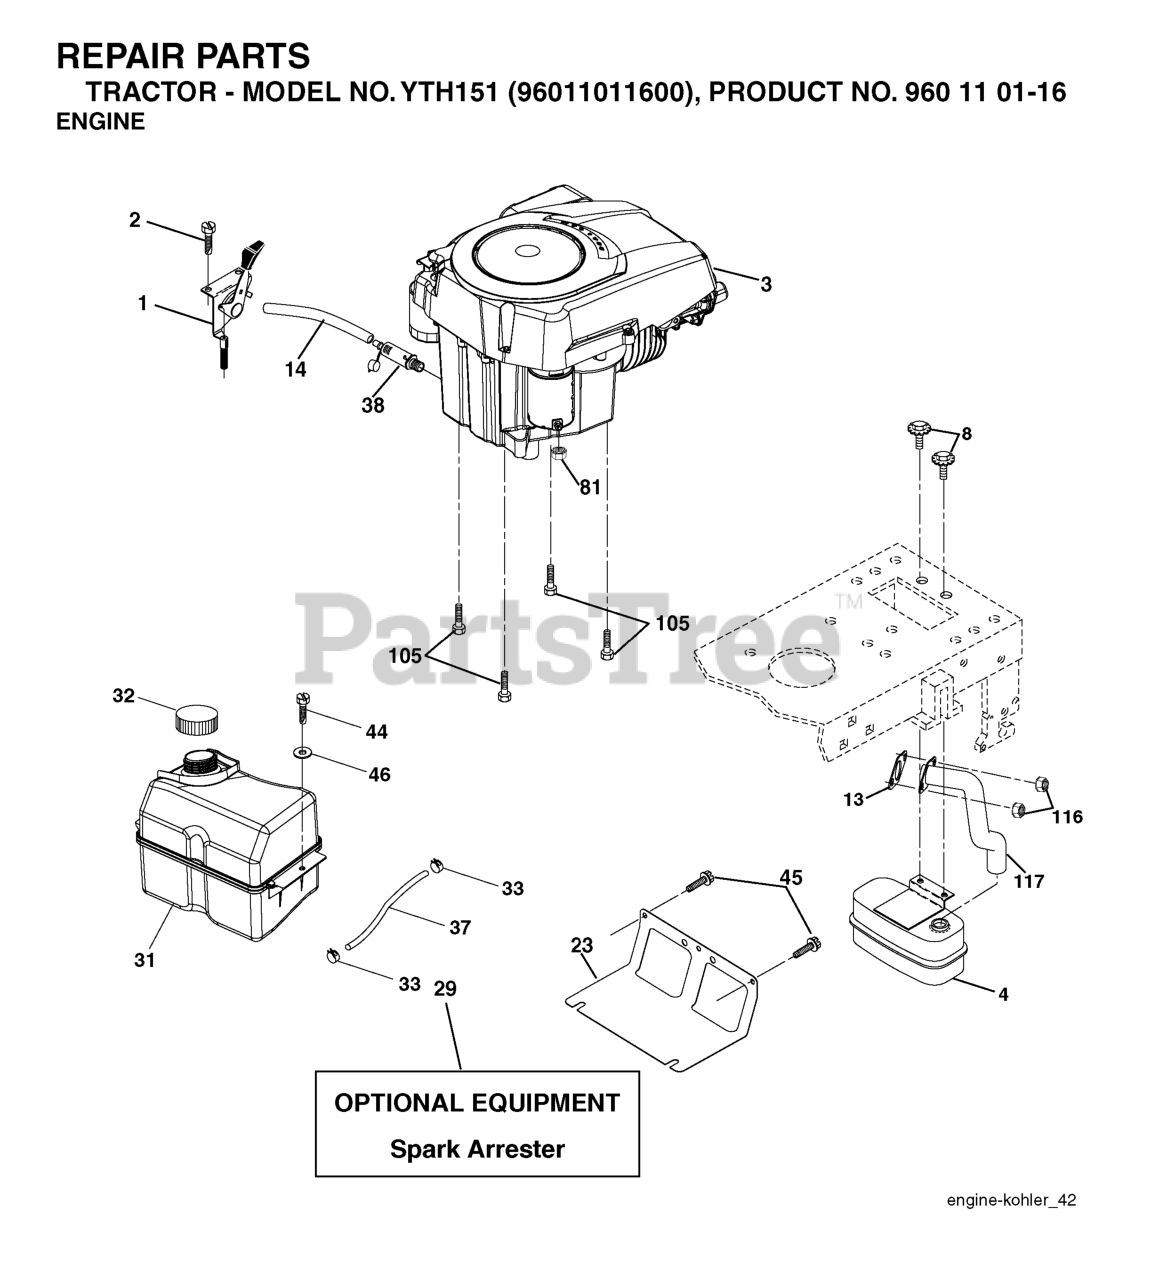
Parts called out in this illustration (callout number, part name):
1	CONTROL.THROTTLE.LT/YT
2	SCREW
4	MUFFLER.SINGLE.CYL.KOHL/B&S
8	BOLT.5/16-18UNCX3/4 W/SEMS.BLK
13	GASKET.EXHAUST.KOHLER
14	TUBE, DRAIN OIL ASM.
23	SHIELD.BROWNING.DBR.GUARD
29	KIT.SPARK ARRESTOR 794945 B&S
31	TANK FUEL
32	FUEL CAP
33	HOSE CLAMP
37	LINE.FUEL.20
38	PLUG DRAIN OIL EASY
44	SCREW HEXWSHR 1/4-20X3/4
45	SCREW, 3/8-16X3/4
81	NUT
105	SCREW 3/8-16X1
116	NUT.HEX.FLANGE.TOPLOCK
117	RP.TUBE.EXHAUST.KOHL.COURAGE
